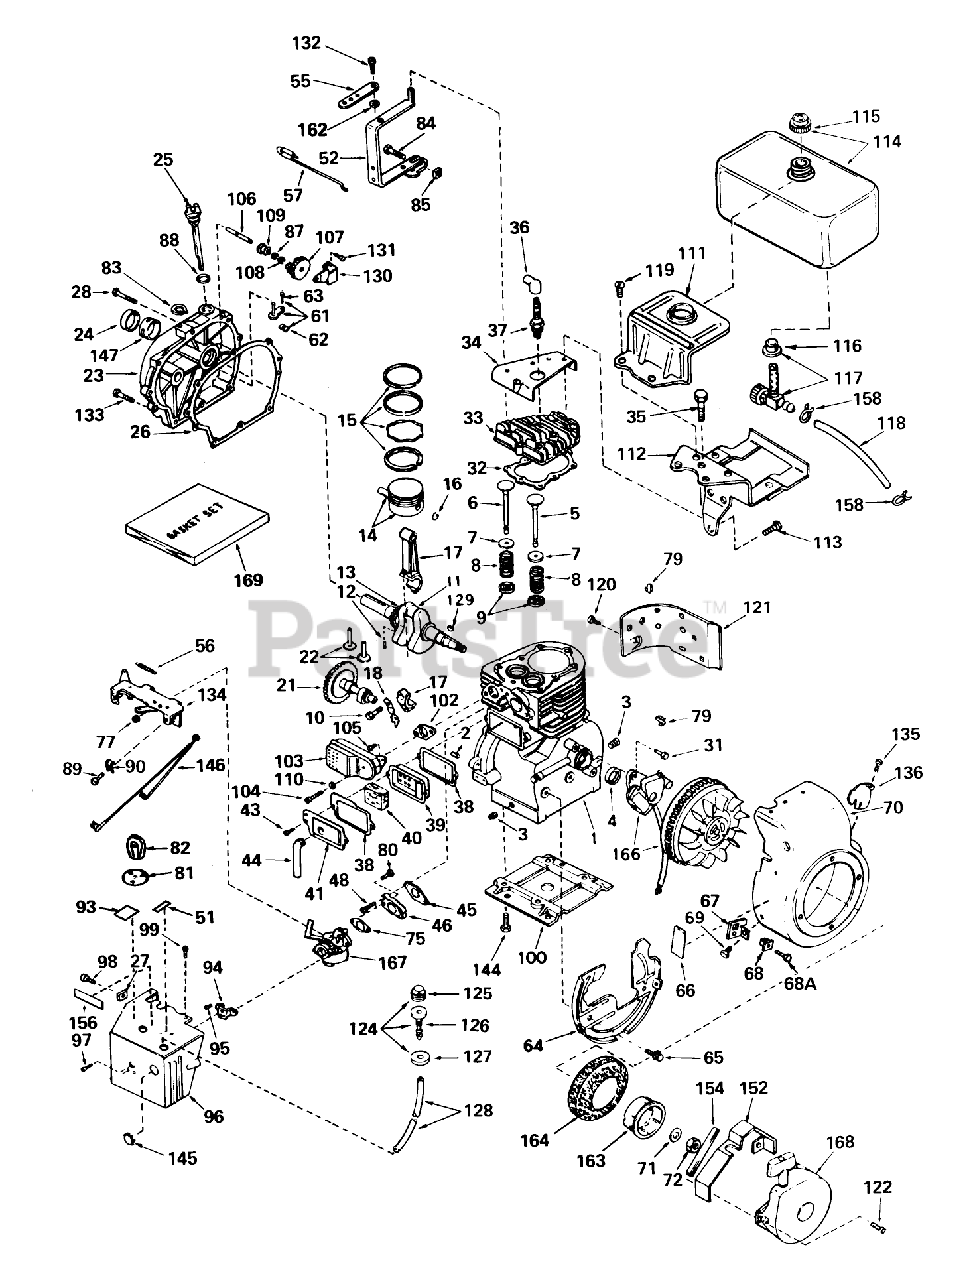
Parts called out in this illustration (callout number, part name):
1	Cylinder Assy. (Incl. Nos. 2, 3 4)
2	Pin-Dowel
3	Plug-Drain, Oil (SQH 1/4-18)
4	Oil Seal
5	Valve, Intake (Standard)(Incl. No. 9)
5	Valve, Intake (1/32" oversize)(Incl. No. 9)
6	Valve, Exhaust (Standard)(Incl. No. 9)
6	Valve, Exhaust (1/32" oversize)(Incl. No. 9)
7	Cap-Spring, Valve
8	Spring-Valve
9	Keeper-Spring, Valve
10	Screw, Hex Hd.
11	Crankshaft Assy. (Incl. Nos. 12 13)
12	Pin, Groove
13	Gear-Crankshaft
14	Piston Pin Assy. (Incl. 2 of No. 16)(Standard)
14	Piston Pin Assy. (Incl. 2 of No. 16)(.010 oversize)
14	Piston Pin Assy. (Incl. 2 of No. 16)(.020 oversize)
15	ORing
15	Ring Set (.010" OS)
15	Ring Set (.020" OS)
17	Rod Assy., Connecting (Incl. Nos. 10 18)
18	Plate, Lock
21	Camshaft
22	Lifter-Valve
23	Cover, Cylinder (Incl. Nos. 24 106)
24	Oil Seal
25	Dipstick, Oil (Incl. No. 30)
26	Gasket-Cover, Cylinder
27	Nut-U Type
28	Screw (1/4-20 x 1-1/4)
31	Screw
32	Gasket-Cylinder Head
33	CYLINDER HEAD
34	Cover-Head, Cylinder
35	Screw Hex Hd. Cap
36	Cover-Spark Plug
37	Plug, Spark (J17LM or equiv.)
38	Gasket-Breather
39	Body-Breather
40	Element-Breather
41	Cover-Valve
43	Screw
44	Tube-Breather
45	Gasket-Intake
46	Flange, Carburetor (Incl. Nos. 77 80)
48	Screw
51	Decal-Primer
52	Lever, Governor
56	Spring, Extension
57	Link, Governor to Throttle
61	Rod, Governor (Incl. Nos.62 63)
62	Yoke-Governor
63	Screw (6-40x5/16)
64	Baffle Blower Housing
65	Screw (1/4-20x19/32)
66	Decal, Instruction
67	Bracket
68	Grommet
68A	Screw
69	Screw, Hex Hd.
70	Housing, Blower (Incl. Nos.135 136)
71	Washer
75	Gasket-Carburetor
77	Nut and Lock Washer (1/4-28)
79	51004 GIL ROTARY TI
80	Screw
81	Plate, Control
82	Knob-Control
83	Ring-Retaining
84	Screw
85	Nut-Lock
87	Washer-Flat
88	Gasket
89	Screw (10-32 x 3/8)
90	Conduit
93	Decal, Warning
94	Bracket-Choke
95	Screw (10-32 x 1/2)
96	Cover, Carburetor
97	Screw (8-32 X 5/16)
98	Screw (8-32 x 3/8)
99	Screw (10-32x1/2)
100	Base Engine
102	Gasket Exhaust
103	Muffler
104	Screw Hex Hd. Cap
105	Screw
106	Shaft-Governor
107	Governor Gear ASM
108	Ring-Retaining
109	Spool-Governor
110	Washer
111	Plate, Fuel Tank Mounting
112	Bracket, Fuel Tank
113	Screw (1/4-20x19/32)
114	Tank Assy., Fuel (Incl. Nos.115 117)
115	Cap, Fuel
116	Bushing, Fuel Fitting
117	Valve, Fuel Strainer Shut-off (Incl. No.116)
118	Line-Fuel
119	Screw, Fil, Slotted Hd. Sems
120	Screw
121	Emnsion, Blower Housing
122	Screw
124	Primer Assy. (Incl. Nos. 89, 90 91)
125	Bulb, Primer
126	Body, Primer
127	Retainer, Primer Bulb
128	Line, Primer
129	Key-Flywheel
130	Bracket, Governor
131	Screw (10-32 x 35/64)
132	Screw
133	Screw
134	Bracket Assy., Speed Control (Incl. No. 56)
135	Screw, Pan Hd.
136	Screw
144	Screw
145	Plug
146	Wire, Ground
147	Bushing-Crankshaft
152	Guard-Starter
154	Seal, Snowguard
156	Decal, Choke
158	Clamp-Line, Fuel
162	Washer-Lock
163	Cup-Starter
164	Screen, Air
166	Magneto
167	Carburetor (Incl. No. 75)
168	Starter Assy., Rewind
169	Gasket Set
